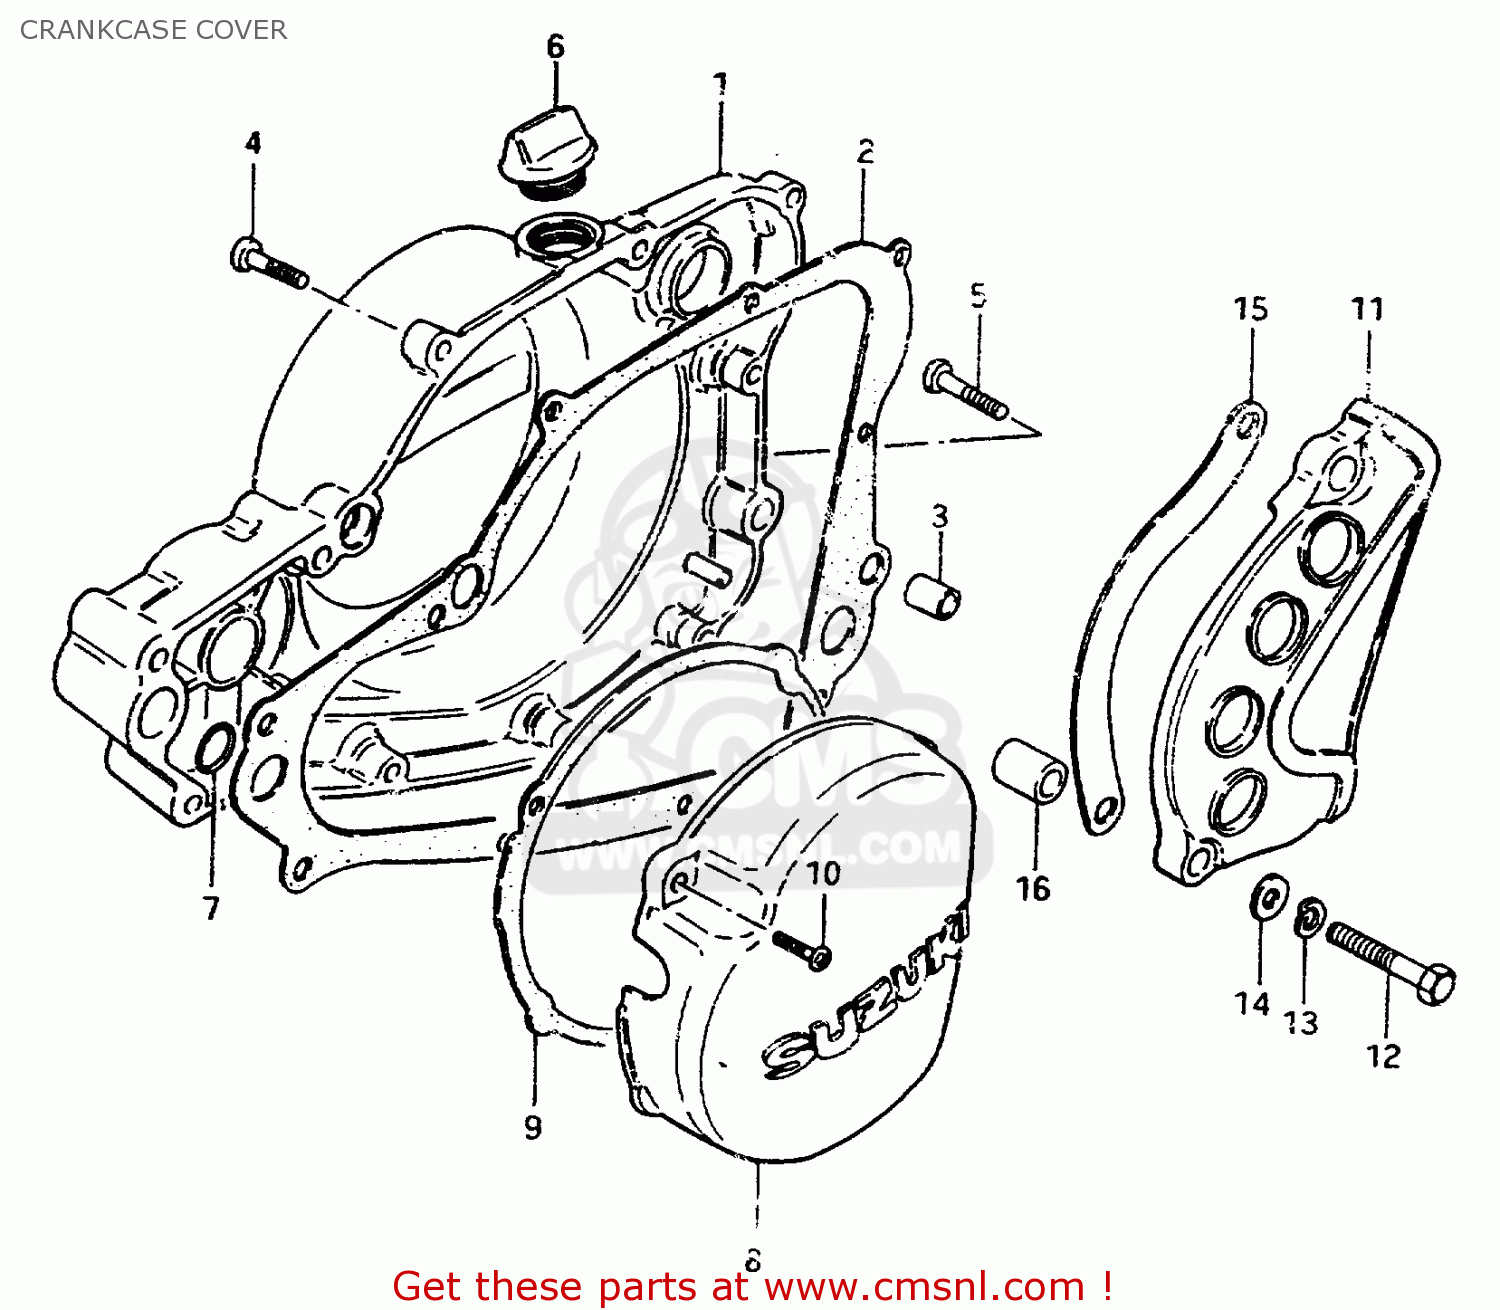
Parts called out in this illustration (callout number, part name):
1	COVER,CLUTCH
2	GASKET,CLUTCH COVER (NAS)
3	PIN
4	SCREW
5	SCREW
6	PLUG SET
7	O RING(D:2.4,ID:16.8)
8	COVER,MAGNETO
9	GASKET,MAGNETO COVER (NAS)
10	SCREW
11	COVER,ENGINE SPROCKET
12	BOLT 8X55
13	WASHER,LOCK,8.
14	WASHER
15	PLATE,FR CHAIN GUIDE
16	SPACER(8.6X16X24)
